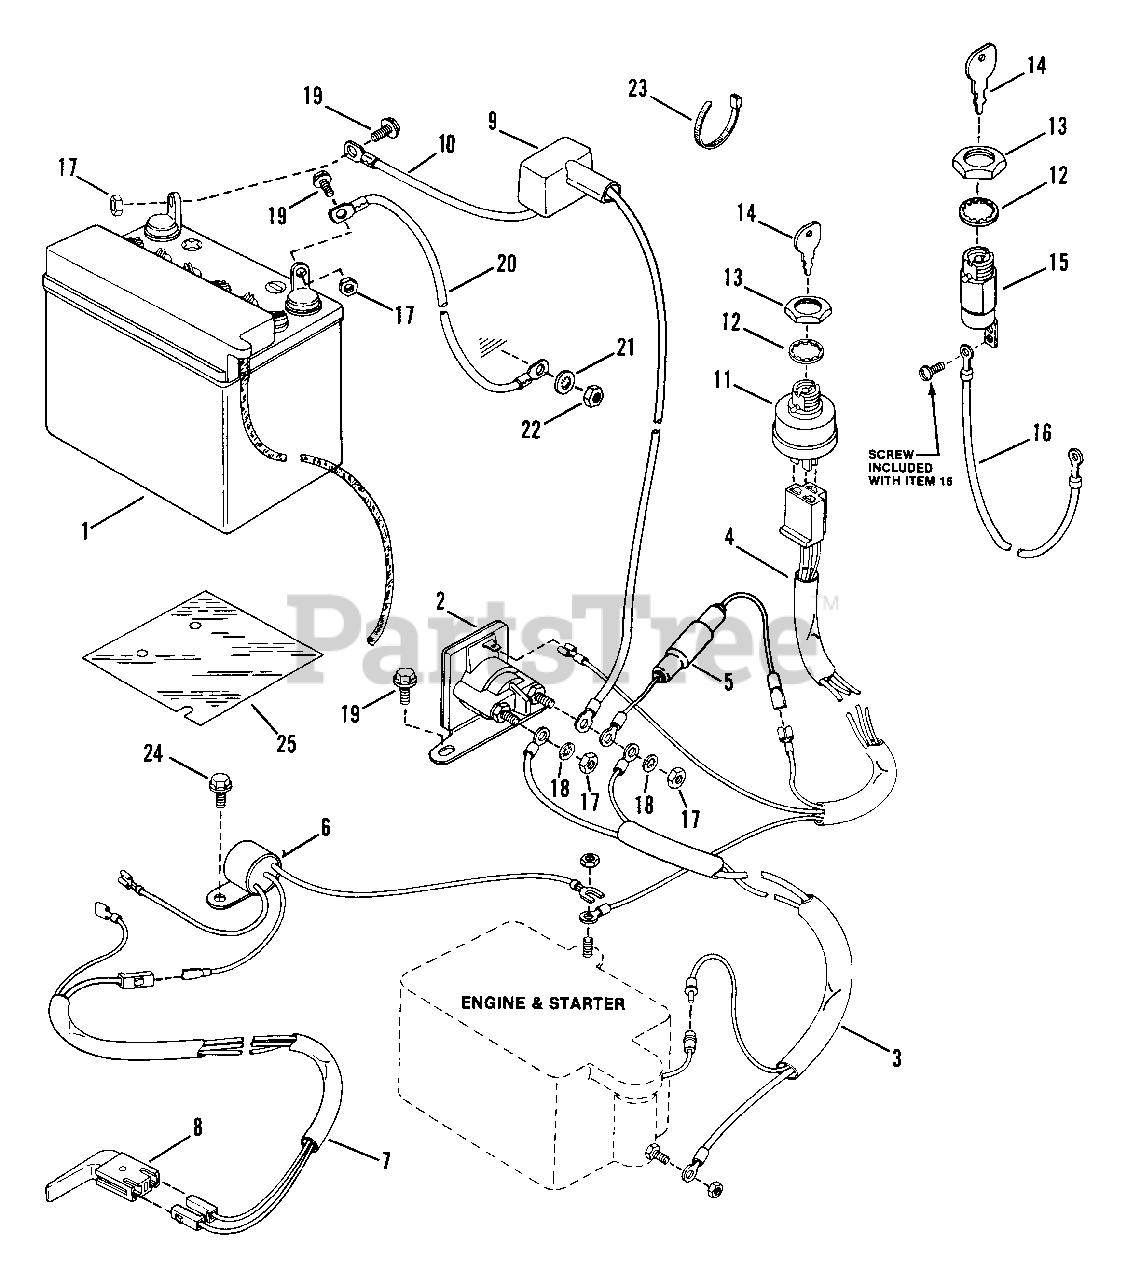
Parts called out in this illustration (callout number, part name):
1	KIT, 12V Dry Charge Battery
2	SOLENOID
3	HARNESS, Starter Wiring
4	HARNESS, Ignition Wiring
5	HOLDER, Fuse
6	INTERLOCK
7	HARNESS, Deck Interlock Wiring
8	SWITCH, Deck Interlock
9	COVER, Battery Cable
10	CABLE, Positive (Red)
11	SWITCH, Ignition
12	WASHER, 5/8 Internal Tooth Lock
13	NUT, 5/8-32 Hex
14	KEY, Switch (With Cover)
15	SWITCH, Ignition
16	WIRE, Ground
17	NUT, 1/4-20 Hex
18	WASHER, 1/4 Internal Tooth Lock
19	SCREW, 1/4-20 x 5/8" Hex Head Cap
20	CABLE, Negative
21	WASHER, 5/16 Internal Tooth Lock
22	NUT, 5/16-18 Hex
23	TIE, Cable
24	SCREW, 1/4-20 x 1/2" Self-Tapping
25	PROTECTOR, Solenoid
